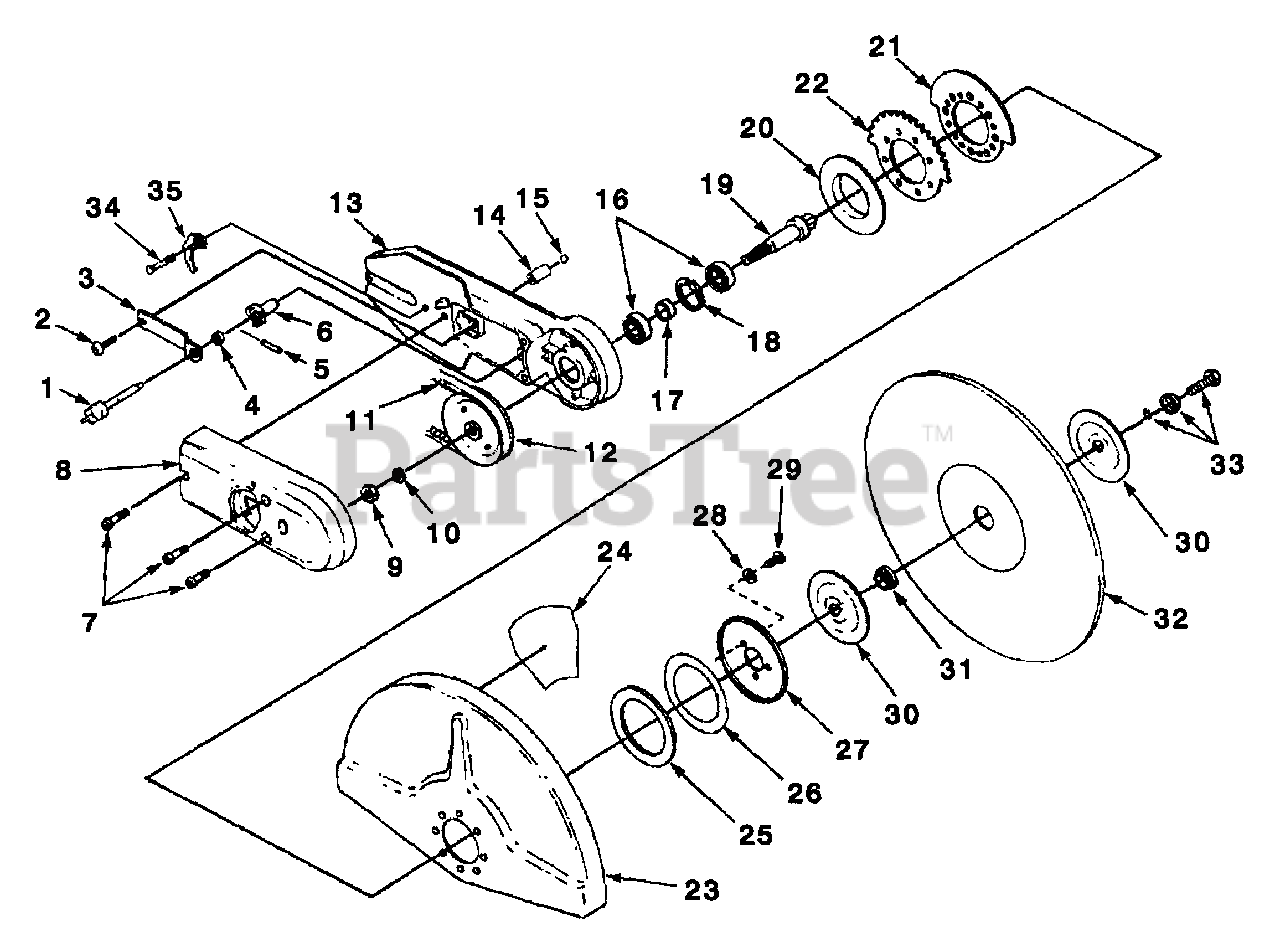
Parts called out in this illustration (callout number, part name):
1	KNOB & PIN
2	SCREW - Truss Hd. (10-24 X 1/2")
3	PLATE - Spring
4	SPACER - Adjusting Pin
5	PIN - Roll
6	SLEEVE - Cam
7	SCREW - Round Hd (10-24 X 23/32")
8	BELT - Cover
9	NUT - Hex
10	WASHER - Lock (7/16)
11	BELT - V-Drive
12	PULLEY & HUB
13	ARM - Wheel
14	SNUBBER
15	STEEL BALL
16	BEARING - Ball
17	SPACER - Bearing
18	RING - Retaining
19	SHAFT - Wheel
20	COLLAR - Wheel Guard
21	PAD - Adjuster
22	DETENT - Adjuster
23	WHEEL GUARD & DECAL / 1/2"
23	WHEEL GUARD & DECAL / 14"
24	DECAL - Caution
25	WASHER - Rubber
26	SHIM - .020"
26	SHIM - .030"
27	WASHER - Spring
28	WASHER (#12-11/16)
29	CREW - Truss Hd (10-24 X 1/2")
30	FLANGE - Wheel
31	SPACER (1")
32	WHEEL
33	BOLT & WASHER
34	CREW - Hex hd (5/16-18 X 1 1/2")
35	CAM & ADJUSTER
